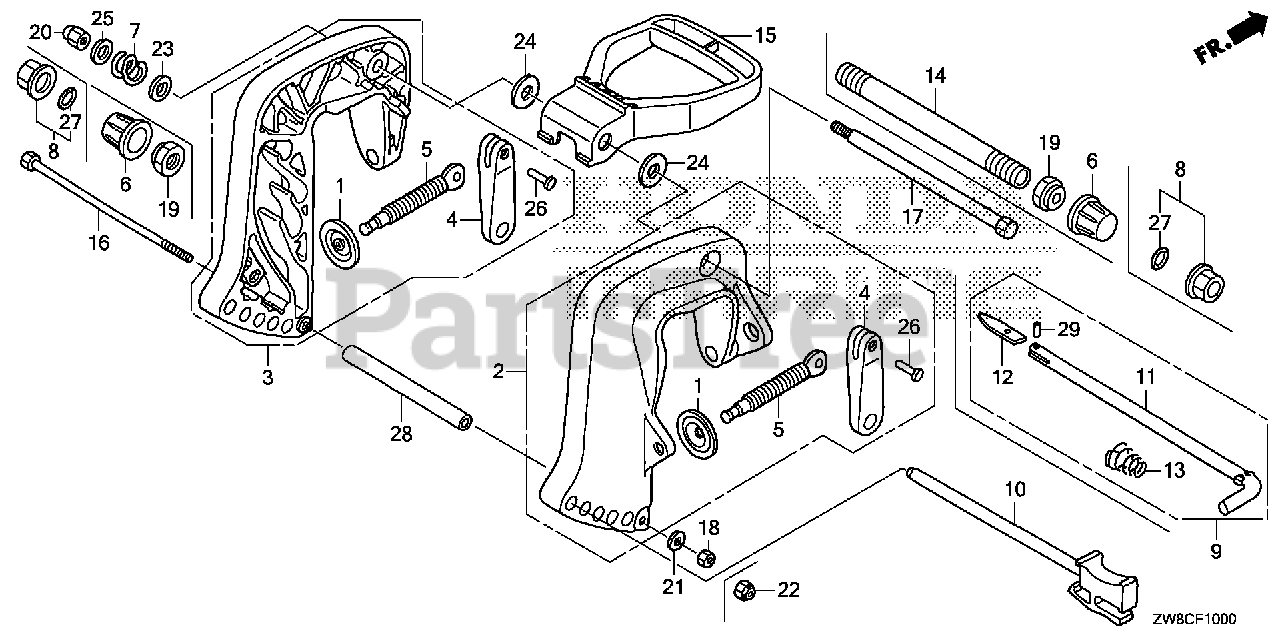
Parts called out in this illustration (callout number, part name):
1	PLATE, PUSH
2	BRACKET, R. STERN *NHB14M* (AQUA MARINE SILVER METALLIC)
3	BRACKET, L. STERN *NHB14M* (AQUA MARINE SILVER METALLIC)
4	GRIP, CLAMP
5	SCREW, CLAMP
9	ROD, ADJUSTING
11	ROD, ADJUSTING
12	STOPPER, ROD
13	SPRING, ADJUSTING ROD
14	SHAFT, TILTING
15	HANDLE, CARRYING REMOTE
16	BOLT, HEX. (8X163)
19	NUT, SELF-LOCK (7/8-14UNF)
21	WASHER, PLAIN (8MM)
22	NUT, SELF-LOCK (8MM)
24	WASHER, WAVE (22MM)
26	RIVET (4X22.6)
27	O-RING (15.54X2.62)
28	COLLAR, DISTANCE (8MM)
29	PIN, SPRING (2.5X8)
